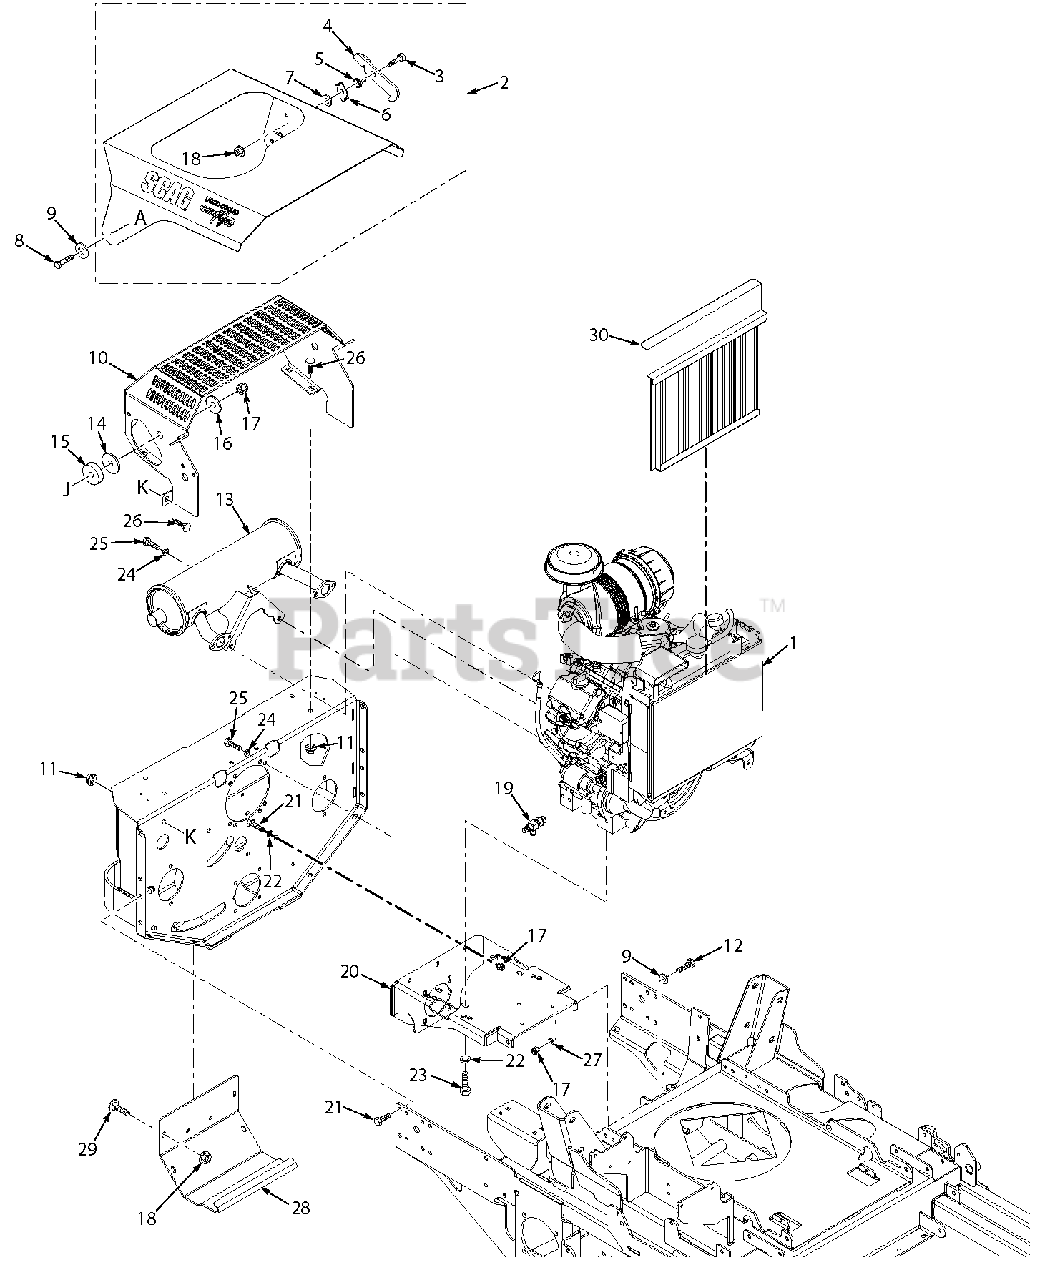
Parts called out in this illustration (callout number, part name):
1	Engine, FD750 - Kawasaki
1	Engine, FD791 - Kawasaki
1	Engine, FD850 - Kawasaki
2	Hood Assy., STTII (FD750)
2	Hood Assy., STTII (FD791 & FD850) - Fuel Injected
3	Bolt, Shoulder 3/8 x 1/2
4	Latch, Hood
5	Spring, Hood Latch
6	Lock, Hood Latch
7	Flatwasher, 3/8-.406 x .812 x .065
8	Bolt, Hex Head 3/8-16 x 1-3/4"
9	Flatwasher, 3/8-.406 x .812 x .065
10	Guard, Muffler
11	Nut, Flange Elastic Stop Nut, 5/16-18
12	Bolt, Hex Head 3/8-16 x 1-1/4"
13	Muffler, Kawasaki
14	Disc, Anti-Friction
15	Spacer, Hood
16	Flatwasher, 3/8-.406 x 1.50 x 7 Gauge
17	Nut, Elastic Stop 3/8-16
18	Nut, Serrated Flange 5/16-18
19	Oil Drain, Kawasaki
20	Plate Weldment, Engine Mount
21	Bolt, Hex Head 3/8-16 x 1"
22	Lockwasher, 7/16
23	Bolt, Hex Head M10-1.5 x 25 Full Thread
24	Lockwasher, 5/16
25	Bolt, Hex Head M8-1.25 x 20
26	Bolt, Carriage 5/16-18 x 3/4"
27	Lockwasher, 3/8
28	Cover, Rear
29	Bolt, Carriage 5/16-18 x 3/4"
30	Screen Weldment, Radiator
